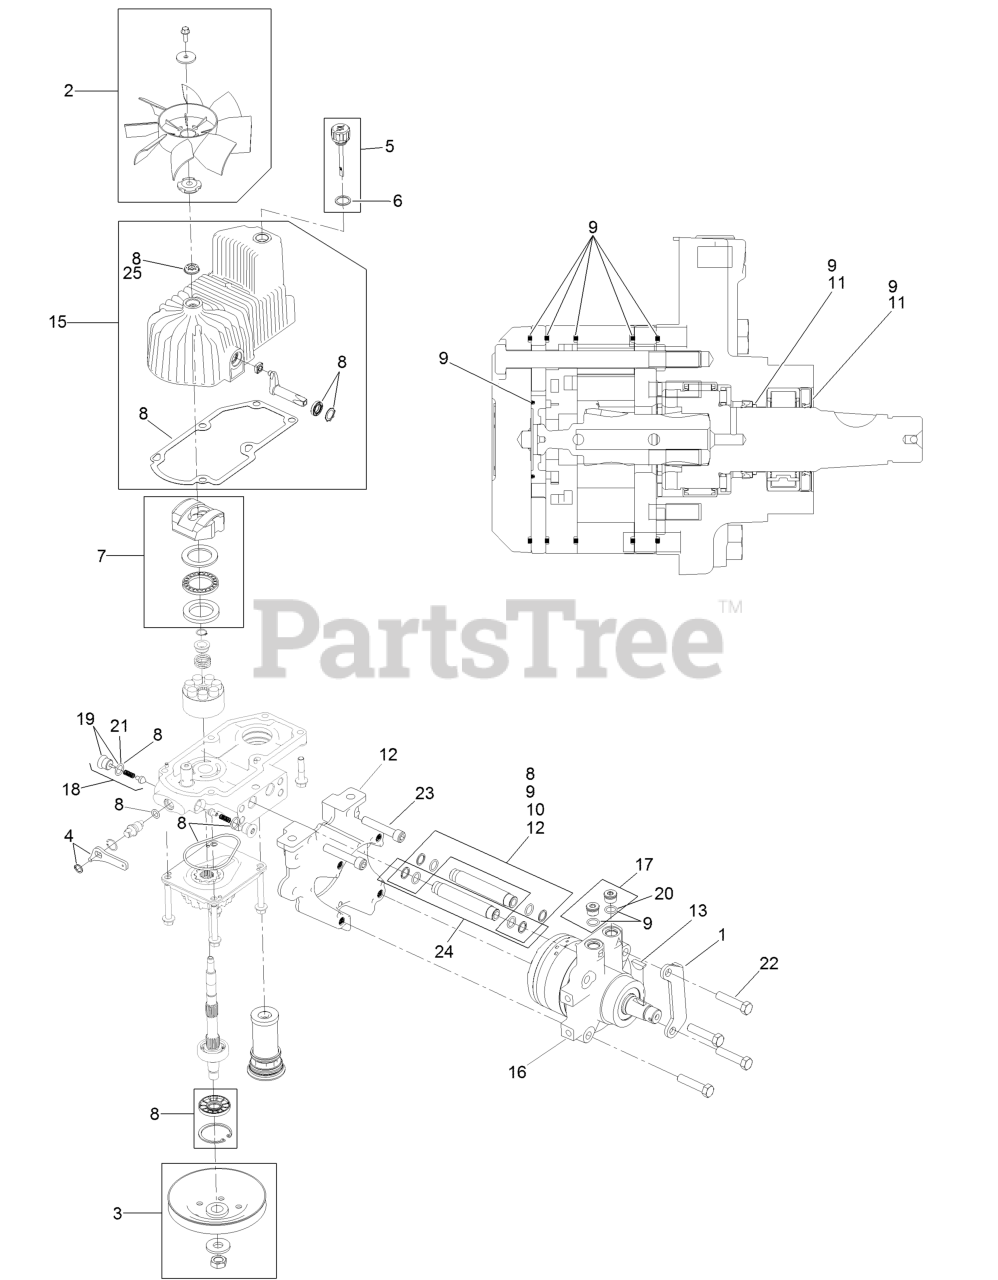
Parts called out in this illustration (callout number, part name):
1	Mount-Shoe, Horse
2	Fan Kit
3	Pulley Kit
4	Handle-Bypass Valve, Hydro
5	Dipstick-Hydro W/Gasket
6	Gasket-Dipstick, Hydro
7	Swash Block Kit
8	Pump Seal Kit
9	Motor Seal Kit
10	Tube Seal Kit
11	Output Shaft Seal Kit
12	Nose Cup-Uht
13	Key-Woodruff
15	Housing-RH
16	Motor-Hydraulic RH 240Cc
17	Magnetic Plugs Service Kit
18	Check Valve ASM
19	Plug-Check (W/O-Ring)
21	O-Ring-Check Valve
22	Screw HH
23	Screw-HSH
24	Hydraulic Tube Kit
25	Seal-Fan Drive
99	Flow Test Kit
99	Puller-Pulley
